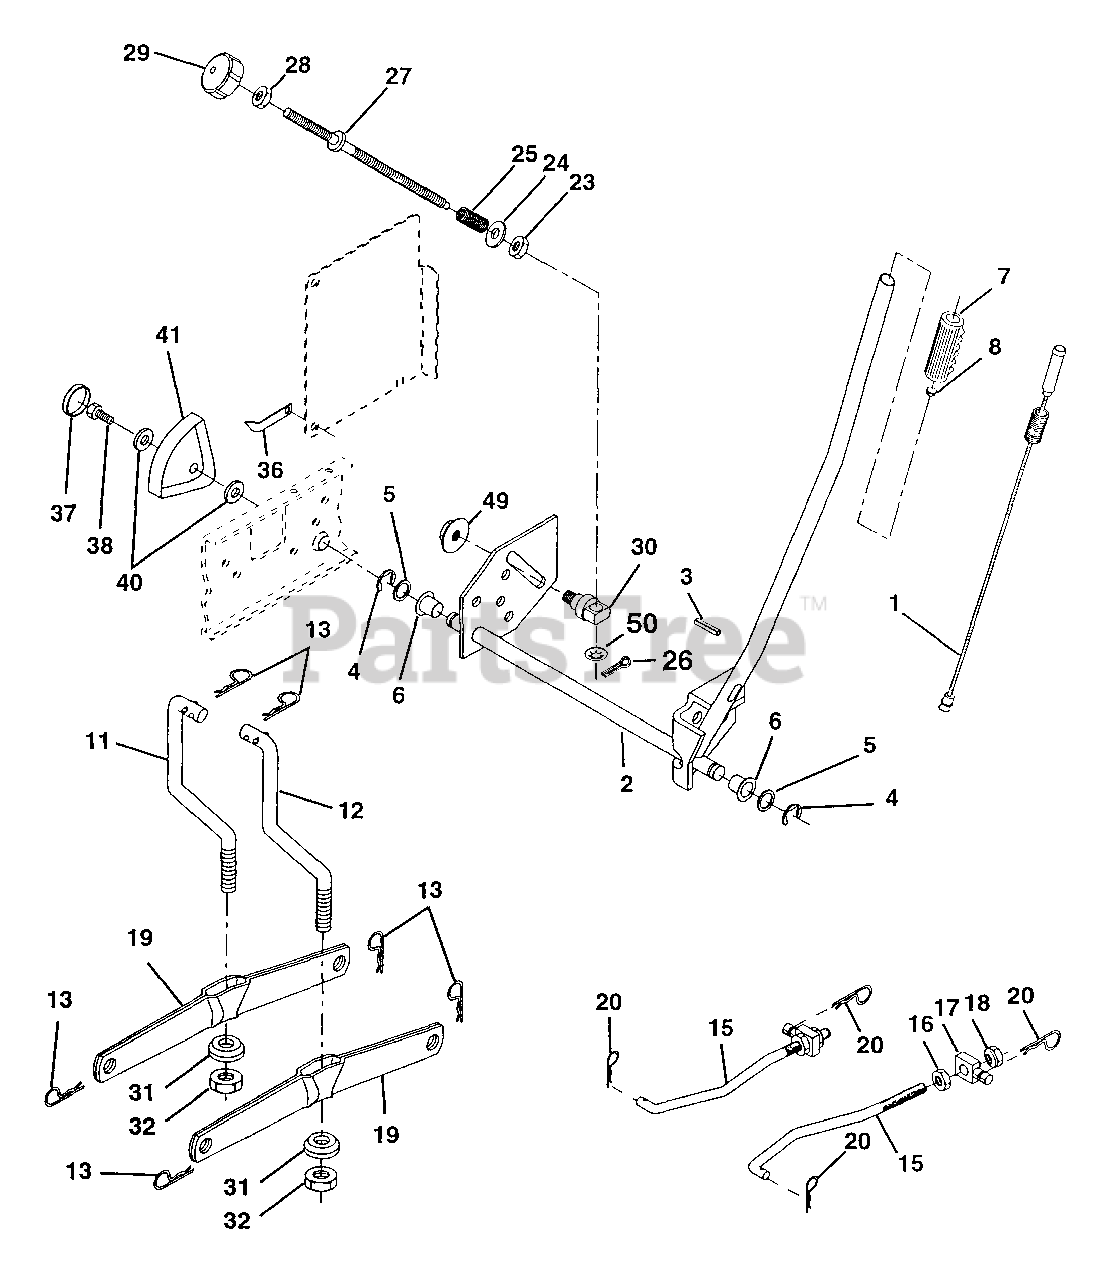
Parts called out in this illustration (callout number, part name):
1	Wire Asm Inner W/plunger
2	Shaft Asm Lift RH
3	Pin Groove 1 500 Zinc
4	E Ring #5133-62 (AYP part number)
5	Washer 21/32 X 1 X 21 Ga
6	Bearing Nylon Blk 629 Id
7	Grip Handle Bicycle Matte Blk
8	Button Plunger Black (AYP part number)
10	Spring Cprsn 3 750 Oiled (AYP part number)
11	Link Lift LH Fixed Length (AYP part number)
12	Link Lift RH Fixed Length
13	Retainer Spring (AYP part number)
15	Link Front
16	Nut Jam Hex 1/2-13 Unc
17	Trunnion Blk Zinc (AYP part number)
18	Nut Lock W/wsh 1/2-13 unc (AYP part number)
19	Arm Suspension Rear
20	Retainer Spring
23	Nut Special
24	Washer 13/32 X 5/8 X 16 Ga
25	Spring 2-1/8"
26	Pin Cotter 3/32 X 1/2 (AYP part number)
27	Rod Adj Lift Zinc 7.49 Wrk Lg (AYP part number)
28	Nut Hex Jam 3/8-16 Unc
29	Knob Inf 3/8-16 Unc Blk W/sym
30	Trunnion Infin Height
31	Bearing Pvt Lift Spherical (AYP part number)
32	Nut Crownlock 3/8 - 24 (AYP part number)
36	Pointer Height Indicator
37	Plug Hole Blk 1.485/1.515 Dia.
38	Screw Thdrol 5/16-18 x 3/4
40	Washer 11/32 x 1-1/2 10 Ga.
41	Indicator Height
49	Nut Hex Flange Lock
50	Nut Push Phos & Oil
